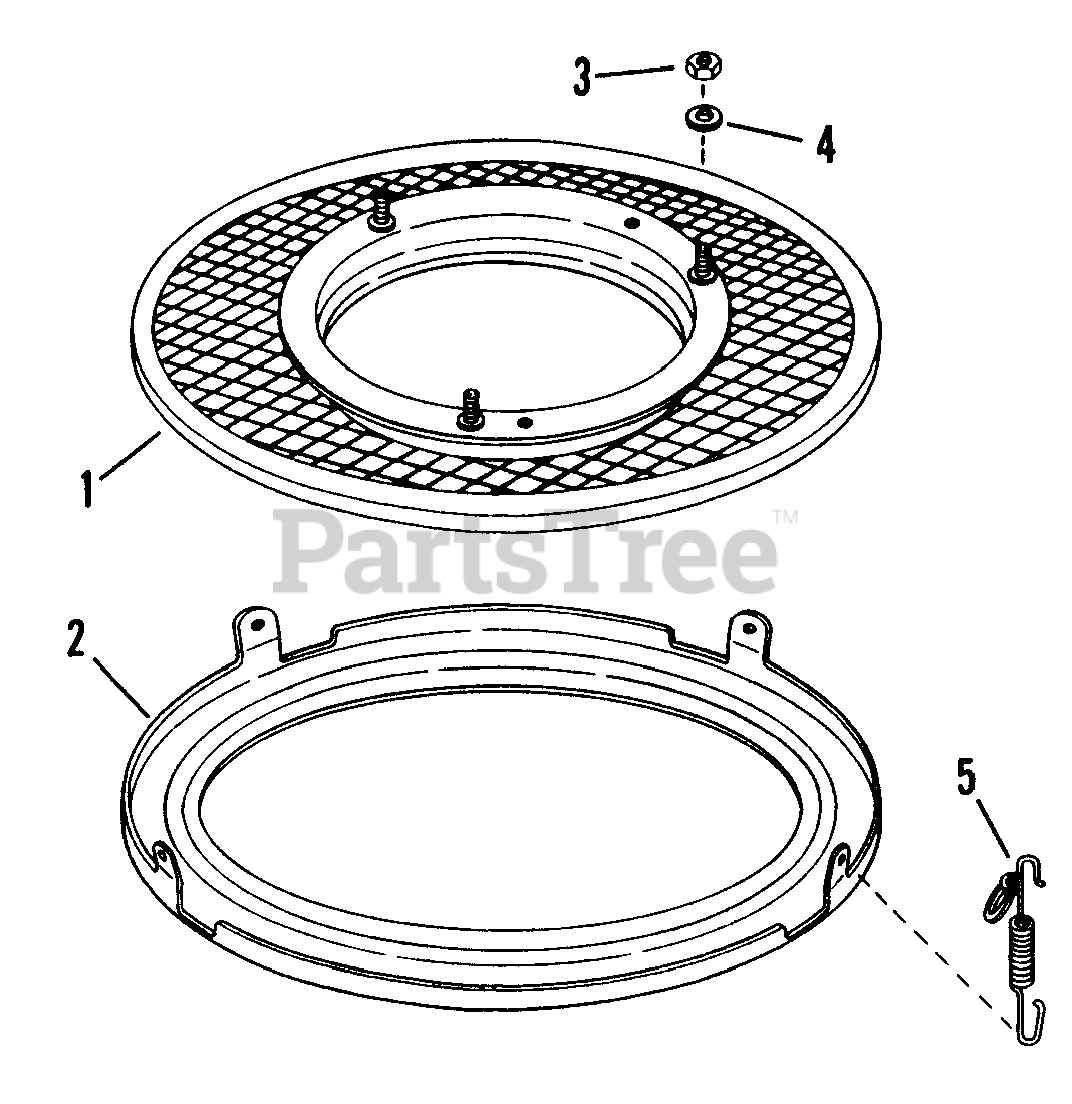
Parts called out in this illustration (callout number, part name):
1	SCREEN, Fastener Assembly
2	RING, Bottom
3	NUT, 5/16 - 24 Hex
4	WASHER, 5/16 - 24 Hex
5	SPRING
